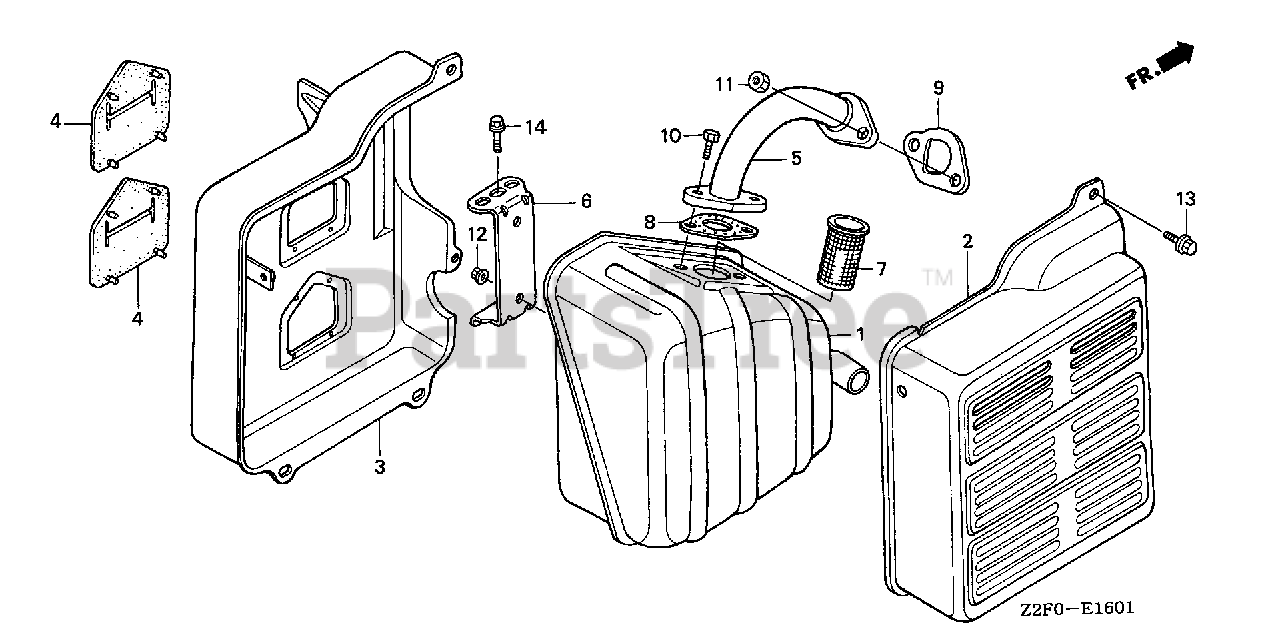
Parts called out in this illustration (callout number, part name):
3	PROTECTOR, MUFFLER (INNER)
4	SEAL, MUFFLER PROTECTOR
6	STAY, MUFFLER
7	ARRESTER, SPARK
8	GASKET, MUFFLER
9	GASKET, MUFFLER
10	BOLT, HEX. (8X20)
11	NUT, HEX. (8MM)
12	NUT, FLANGE (6MM)
14	BOLT, FLANGE (8X20)
